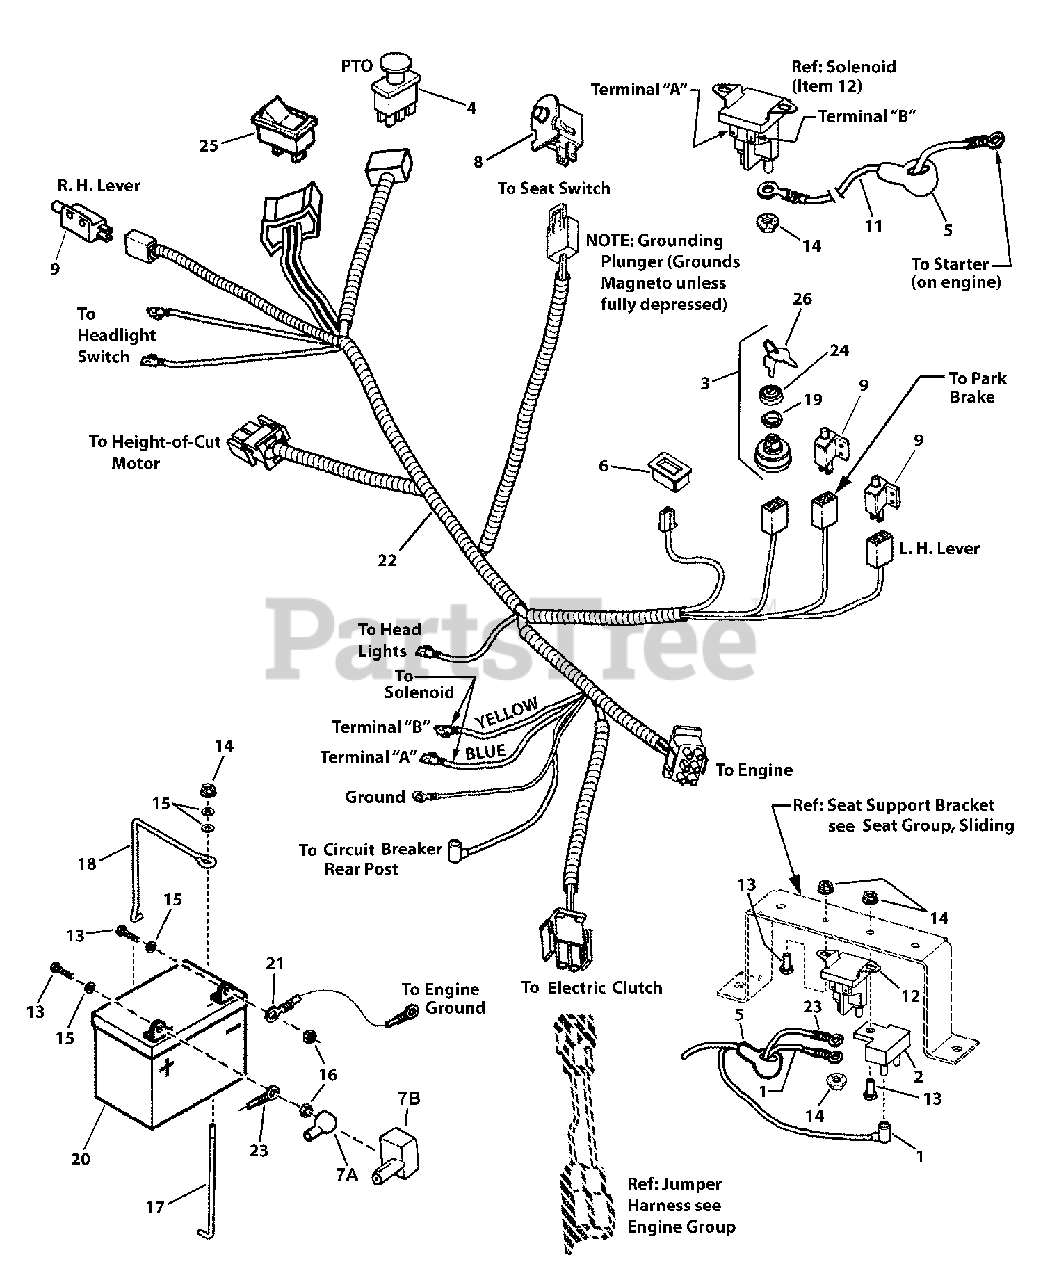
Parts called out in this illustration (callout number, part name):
1	WIRE, 12 Gage, 8", Red
2	BREAKER, Circuit 12 Volt 20 AMP w/Tab
3	SWITCH ASSEMBLY, Ignition, Indak No Keys/Hdwr
4	SWITCH, PTO, Push/Pull Symbols
5	COVER, Terminal, Red Vinyl
6	HOUR METER
7A	BOOT, Insulator, Battery Terminal, PVC, Red
7B	COVER, Battery Cover
8	SWITCH, Push Button (NC) (gray)
9	SWITCH, DPDT (NC/NO) (Gray)
11	CABLE, Starter, 8 Gage, 14, Black
12	SOLENOID, Super Trombetta - 2 Terminal
13	SCREW, 1/4-20 x 5/8" Hex Head Cap, GR 5
14	NUT, 1/4-20 Hex Flange Lock, YZ
15	WASHER, 1/4" Flat
16	NUT, 1/4-20 Hex Center Lock, GR B
17	HOLD DOWN, Battery
18	BRACKET, Battery
19	NUT, 5/8"-32 E-Start
20	BATTERY, 12 Volt, 230 CCA
21	CABLE, Battery, Negative, 8 Gage, 20" Black
22	HARNESS, Wiring
23	CABLE, Battery, Positive, 8 Gage, Red
24	CAP, Ignition Switch
25	SWITCH, Rocker Electric Height-Of-Cut
26	KEYS, Blister Pk (KIDS+MWRS DON'T MIX) English/Spanish (set of two, one coated)
